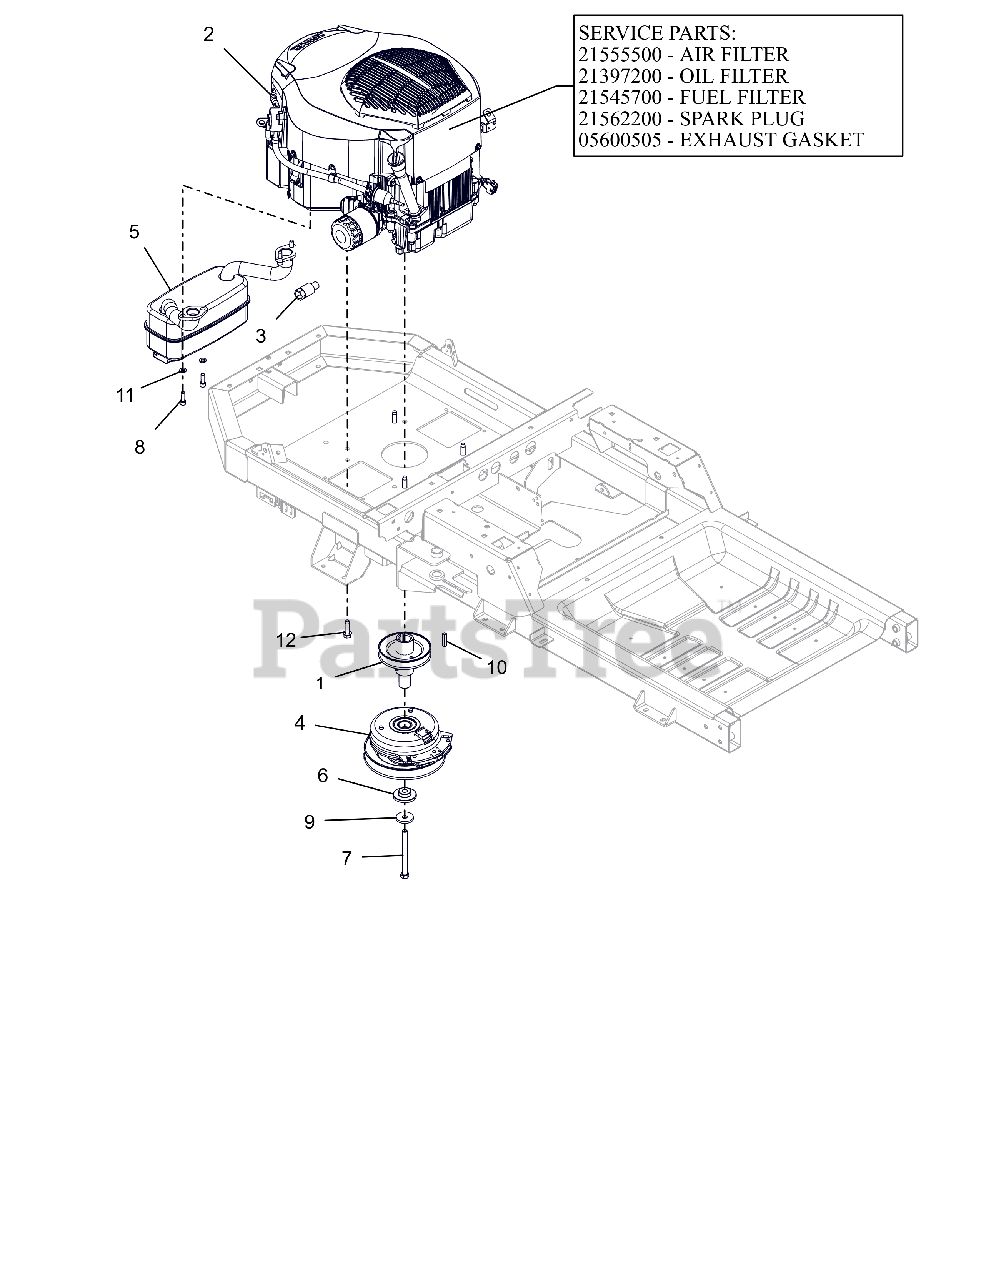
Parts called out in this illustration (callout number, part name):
1	WLDMT, DRIVE SHEAVE-X
2	ENGINE, KOHLER 24HP TWIN
2	AIR CLEANER, KOHLER
2	FILTER, OIL - KOH CV20
2	FILTER-FUEL KOHLER COURAGE PRO
2	PLUG, SPARK (RFI)
2	GASKET, MUFFLER COURAGE TWIN
3	DRAIN, OIL
4	CLUTCH,105FTLB MONOPOLE 6.83"
5	MUFFLER - KOHLER
6	BSHG-FLG .469X1.06X.574X2.0
7	BLT-HEX.438-20X4.5GR8YZ NYTORQ
8	SCR-CAP .31-18X.88 S/HD G8 ZCC
9	WASHER, 7/16" SPRING DISK
10	KEY-SQ .25 X 1.25 X .25 SAE
11	WSHR,LK-REG .312X.078 ZCC
12	SCR,TAP .375-16X1.25HWH TR ZCC
